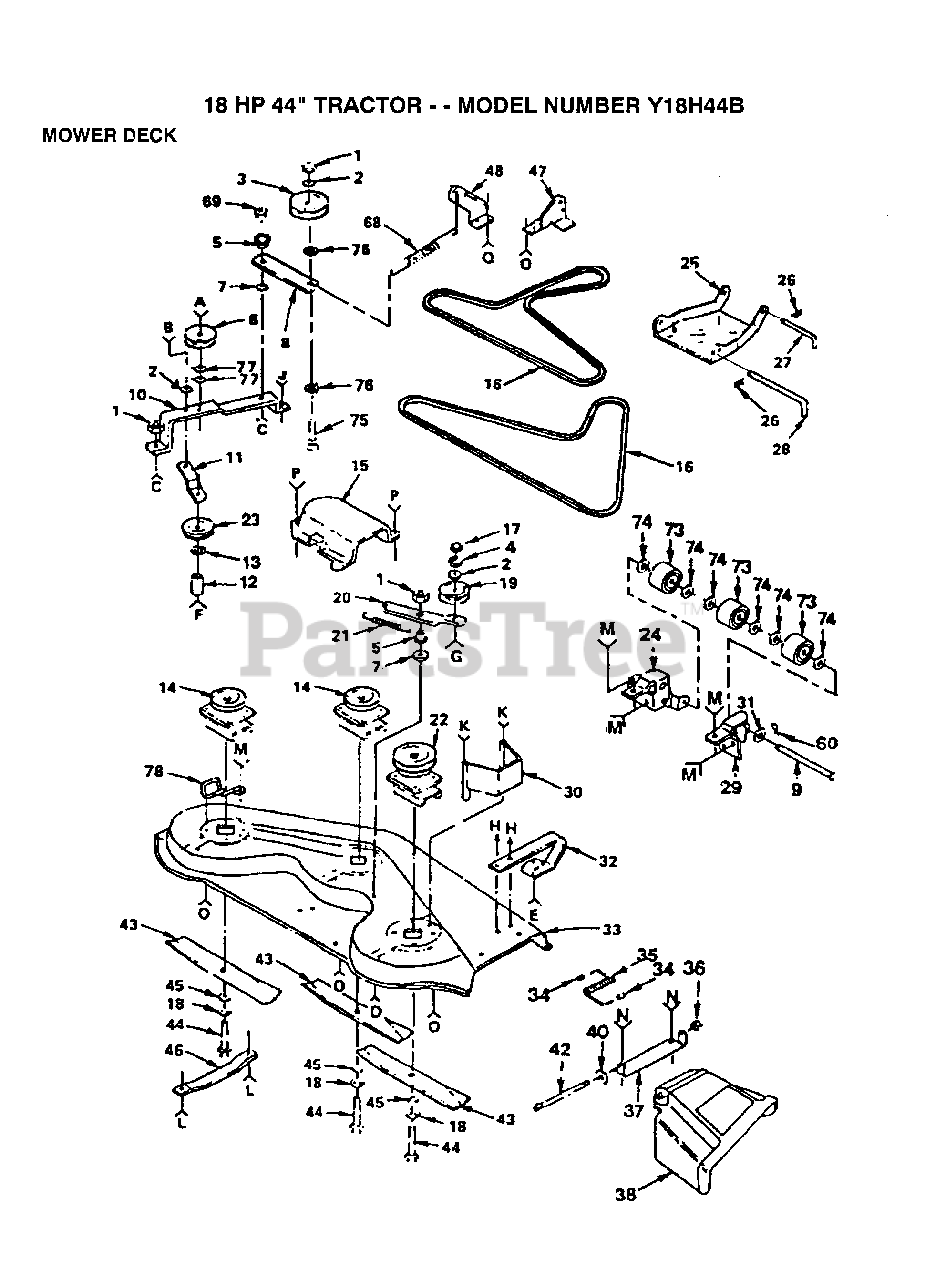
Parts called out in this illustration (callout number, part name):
2	WASHER
3	PULLEY IDLER
4	LOCKWASHER
5	SPACER RETAINER
6	IDLER-INSIDE T
7	"WASHER, WEAR LT"
8	ARM IDLER
9	PIVOT PIN T
10	"SUPPORT YT, BAR"
11	BRACE-IDLER YT
12	SPACER
13	WASHER
15	GUARD YT
16	BELT-V.79.1.MWR
17	NUT.HEX.3/8-16UNC
19	IDLER.FLAT.GTV
20	ARM-IDLER YT
23	IDLER-FLAT T
24	BRACKET LH YTH
25	LINK.PARALLEL
26	SPRING.RETAINER
27	"ROD, FRT. PARAL T"
28	HINGE PIN T
29	BRACKET RH YTH
30	GUARD BELT HYT
34	CAP-SLEEVE LT
36	NUT PUSH M
38	DEFLECTOR SHIELD
40	WASHER
42	ROD-HINGE T
44	BOLT.3/8-24X1-1/2
45	WASHER
46	RUNNER-LH M
47	BRKT SUSP REAR RH
48	BRKT SUSP REAR LH
60	COTTER PIN
68	"SPRING.EXT.8.5"""
69	LOCKNUT
73	ROLLER T
74	WASHER T
75	BOLT
76	WASHER
77	WASHER
78	BELT RETIANER
